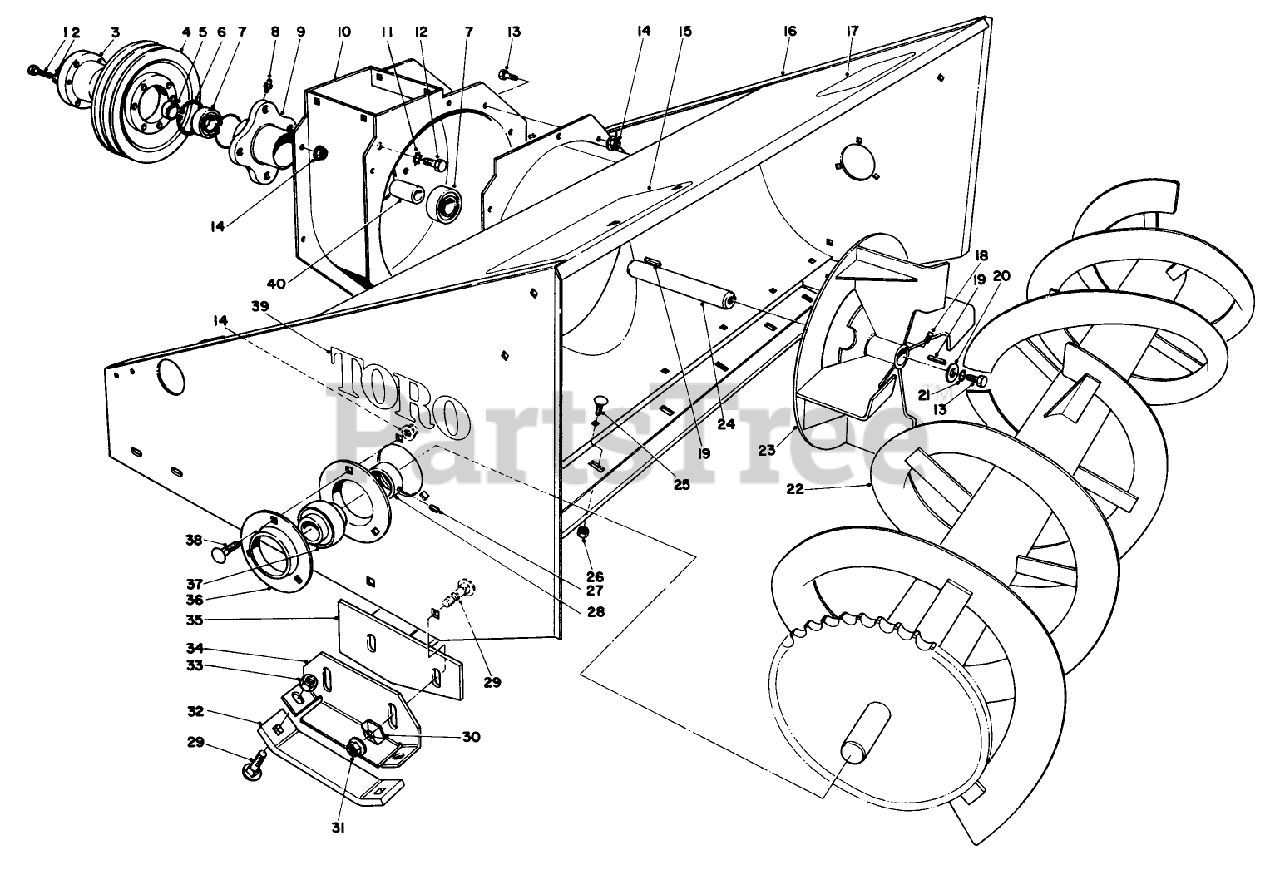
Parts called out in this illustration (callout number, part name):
1	SCREW-HH
2	SCREW-HH
7	BEARING
8	FITTING-LUBE, 45 DEG
11	WASHER-LOCK, EXT
12	SCREW-HH
13	SCREW-HH
14	NUT-HF
18	SCREW-HH
20	WASHER
21	SCREW-HH
25	BOLT-CARR
26	NUT-LOCK, NI
27	SCREW-SET, HSH
28	COLLAR-LOCK, BEARING
29	SCREW-HH
30	LOCKWASHER-PYRAMID
33	NUT-LOCK, CONE
37	BEARING
38	SCREW-CARR
